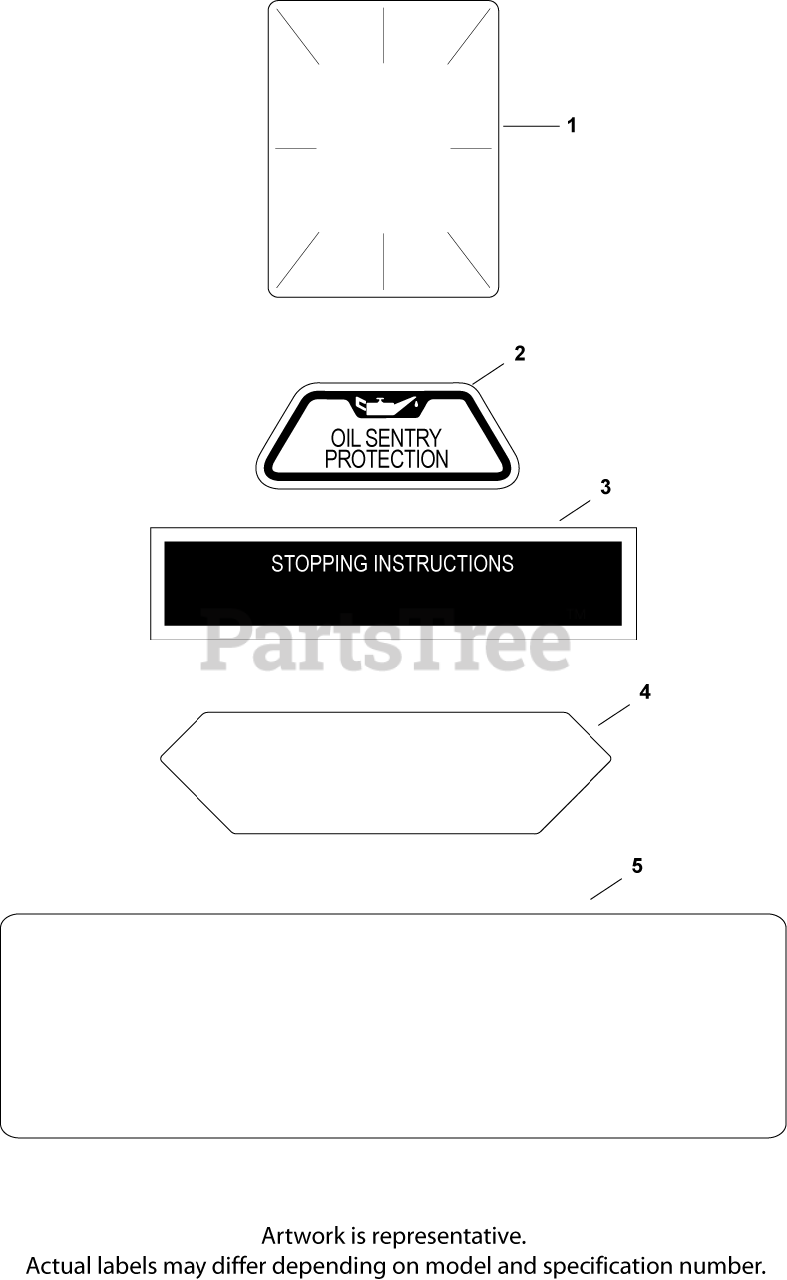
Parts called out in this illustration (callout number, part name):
1	DECAL, CLEAR LAMINATE USE 25 113 70-S
2	DECAL, OIL SENTRY - (#DSC)
3	DECAL, STOPPING INSTRUCTION
4	DECAL, AIR FILTER COVER - DISC.
5	DECAL, 18 HP
